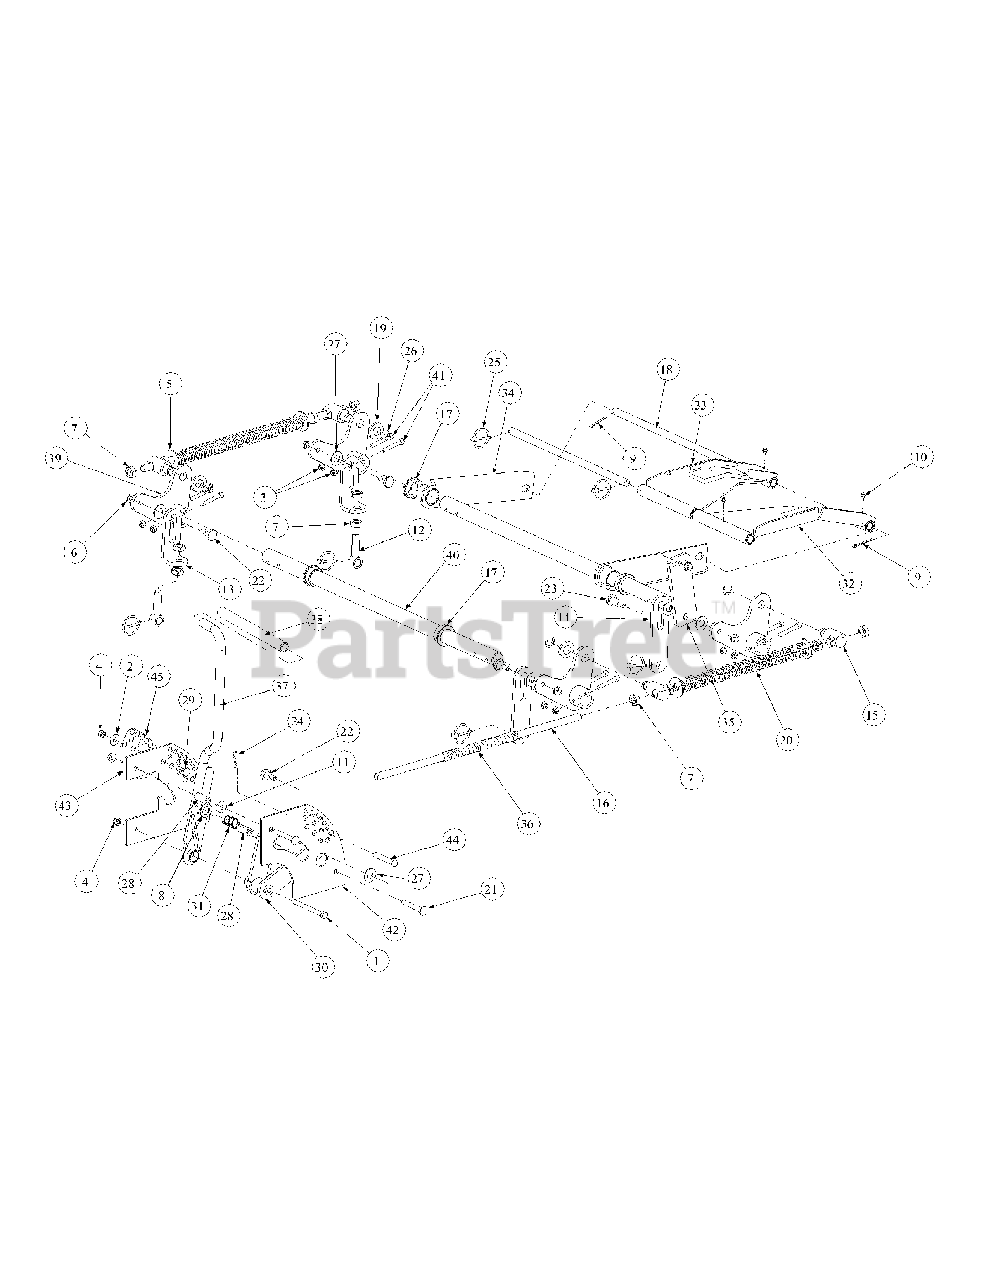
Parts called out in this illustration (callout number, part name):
1	Hex Cap Screw, 3/8-16, 3.75
2	Flat Washer, 3/8
3	Nut, 5/16-18, Nylock
4	Nylock Insert Lock Nut, 3/8-16
5	Flat Washer, 5/8
6	Hex Nut, Flange Lock, 3/8-16
7	Jam Nut, 5/8-11
8	Flat Washer, .06, .776, 1.25
9	Cotter Pin, 3/16 x 1-1
10	Grease Fitting, 1/4-28 x 3/16
11	Idler Washer
12	Eye Bolt, 5/8ID
13	Eye Bolt Mount Link, 5/8 ID
14	Deck Link
15	Ferule Lift
16	Lift Connector Rod
17	Hex Flange Bearing, 1.25 ID
18	Front Lift Link, Rod Mount
19	Spacer, .812 ID x .268 Lg.
20	Lift Compression Spring
21	Carriage Bolt, 3/8-16, 2.75
22	Shoulder Screw, 0.625 OD x .437 Lg.
23	Shoulder Screw, 0.625 OD x .830 Lg.
24	Cotter Pin, .148 x 3.00
25	Linch Pin, 3/16 Dia.
26	E Clip, 3/4 Dia.
27	Nylon Flat Washer, 5/8
28	Spacer, .39 ID x .63 OD x 1.442
29	Shoulder Screw,.50 OD x 0.27
30	Lift Pivot Assembly
31	Lift Handle Spring
32	Bearing Lift Brace Assembly, Right Hand
33	Bearing Lift Brace Assembly, Left Hand
34	Front Frame Strut Assembly
35	Lift Link Adjustment
36	Hose, 5/8 ID 13/16 OD, 8" LG
37	Lift Handle Assembly
38	Lift Handle Grip
39	Bellecrank Weldment Assembly
40	Deck Lift Shaft
41	Socket Head Cap Screw, 5/16-18 x 2
42	Outer Lift Index Plate
43	Inner Lift Index Plate
44	Clevis Pin,.438 Dia. x 2.625 Lg.
45	Decal Height Indicator
